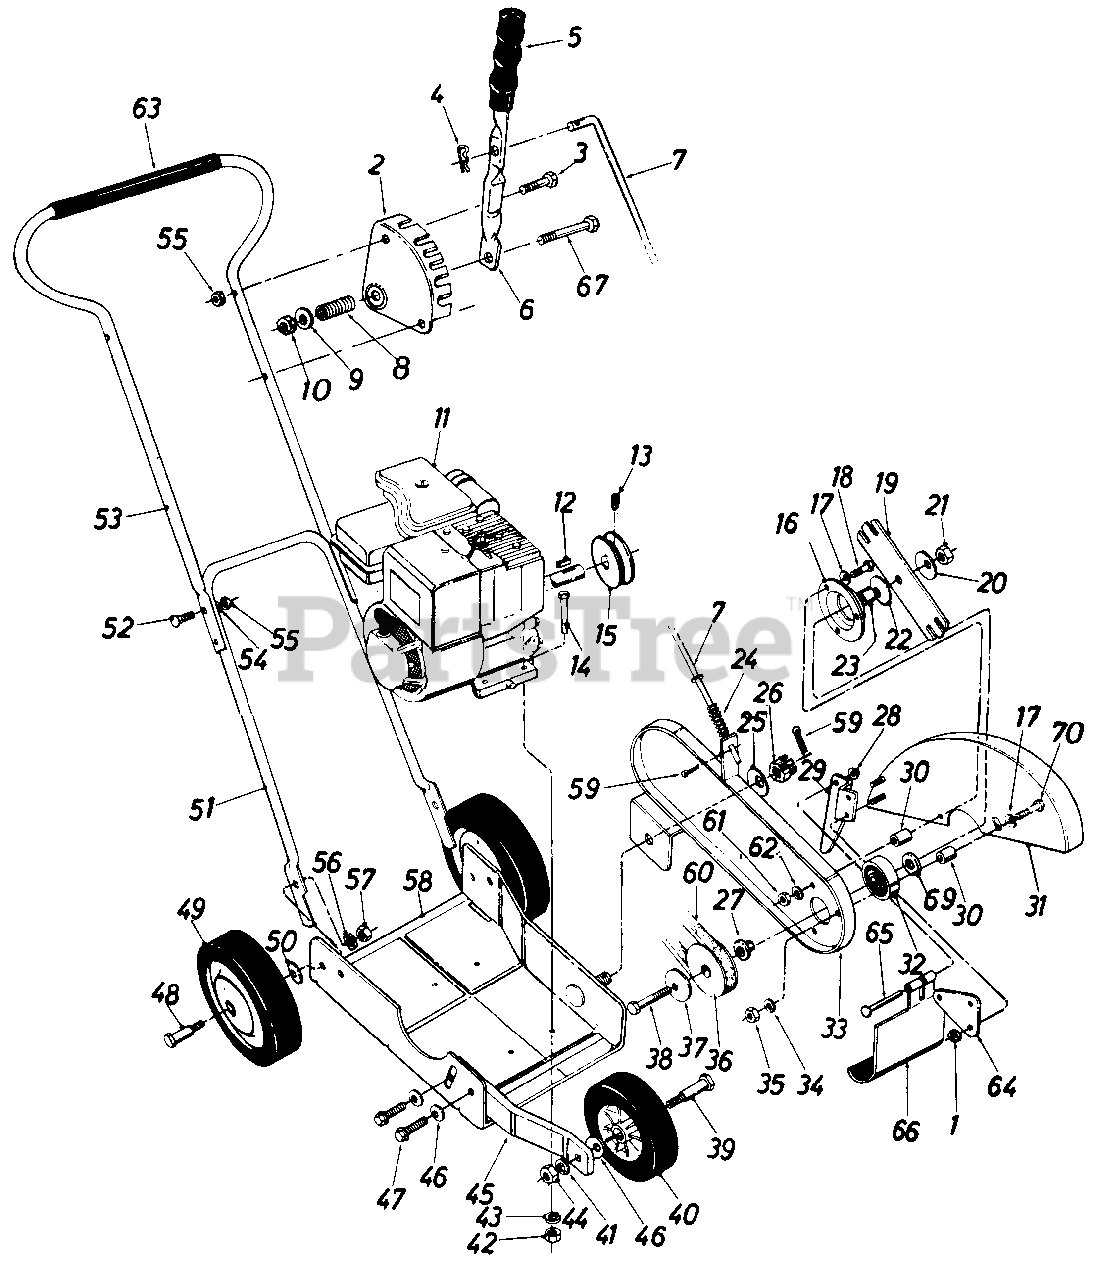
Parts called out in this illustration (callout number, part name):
1	Hex Cent. L.-Nut 1/4-20 Thd.
3	Hex Bolt 1/4-20 x 1.25" Lg.
4	Cotter Pin 1/8" Dia. x 1.0" Lg.
5	Grip
7	Clutch Rod
8	Compression Spring .50" 0. D. x 1.38" Lg.
9	Fl.-Wash. .34" I.D. x .62" O.D. x .063
10	Hex Cent. L.-Nut 5/16-18 Thd.
11	Engine
12	Sq.Key 3/16 x 1.0" Lg.
13	Set Scr. 1/4-28 x 1/4" Lg.
14	Hex Bolt 5/16-18 x 1.50' Lg.
15	Engine Pulley
16	Bearing Housing
17	Bell.-Wash. .34" I.D. x 88" O.D. x .060
18	Hex Bolt 5/16-18 x 1.25" Lg.
20	Bell.-Wash. .535" I.D. x 1.50" O.D. x.052
21	Hex Cent. L.-Nut 1/2-20 Thd.
22	Bell.-Wash. .535" I.D. x 1.50" O.D. x 052
23	Spacer
24	Compression Spring .57" O.D. x 1.92" Lg.
25	Bell.-Wash. .535" I.D. x 1.50" O.D. x .052
26	Hex Castle Nut 1/2-20 Thd.
27	Shoulder Spacer
28	Push Cap
29	Guide
30	Spacer.354" I.D. x .635" O.D. x .510" Lg.
33	Spindle Bracket Ass'y.
34	L.-Wash. 5/16" I.D.
35	Hex Nut 5/16-18 Thd.
36	Pulley
37	Bell.-Wash. .535" I.D. x 1.50" O.D. x.052
38	Hex Bolt 1/2-20 x 3.50" Lg.
39	Shoulder Bolt .498" Dia. x 1.450
40	Wheel Ass'y. Comp. 6" Dia. x 1.50
41	L.-Wash. 3/8" I.D.
42	Hex Nut 5/16-18 Thd.
43	L.-Wash. 5/16" I.D.
44	Hex Nut 3/8-16 Thd.
45	Front Wheel Support
46	Bell.-Wash. .400" I.D. x 88" O.D. x.060
47	Hex Wash. Hd. Self Tap Scr. 3/8-1 6 x . 75 " Lg.
48	Shoulder Bolt.498" Dia. x 1.450
49	Wheel Ass'y. Comp. 7" Dia. x 1.50
50	Bell.-Wash. .400" I.D. x 88' 0. D.
51	Lower Handle
52	Carriage Bolt 1/4-20 x 1.25" Lg.
53	Upper Handle
54	L.-Wash. 1/4" I.D.
55	Hex Nut 1/4-20 Thd.
56	L.-Wash. 3/8" I.D.
57	Hex Nut 3/8-16 Thd.
58	Base Ass'y.
59	Cotter Pin 1/8" Dia. x 1.0" Lg.
60	3V-Belt 31.2" Lg.
61	Hex Nut 5/16-18 Thd.#
62	L.-Wash. 5/16" I.D.
63	Grip
64	Flap Bracket
65	Hinge Pin
66	Debris Deflector
67	Hex Bolt 5/16-18 x 1.75" Lg.
69	Fl.-Wash. .51 I.D. x 1.00 O.D. x .060
70	Hex Bolt 5/16-18 x 2.00" Lg.
